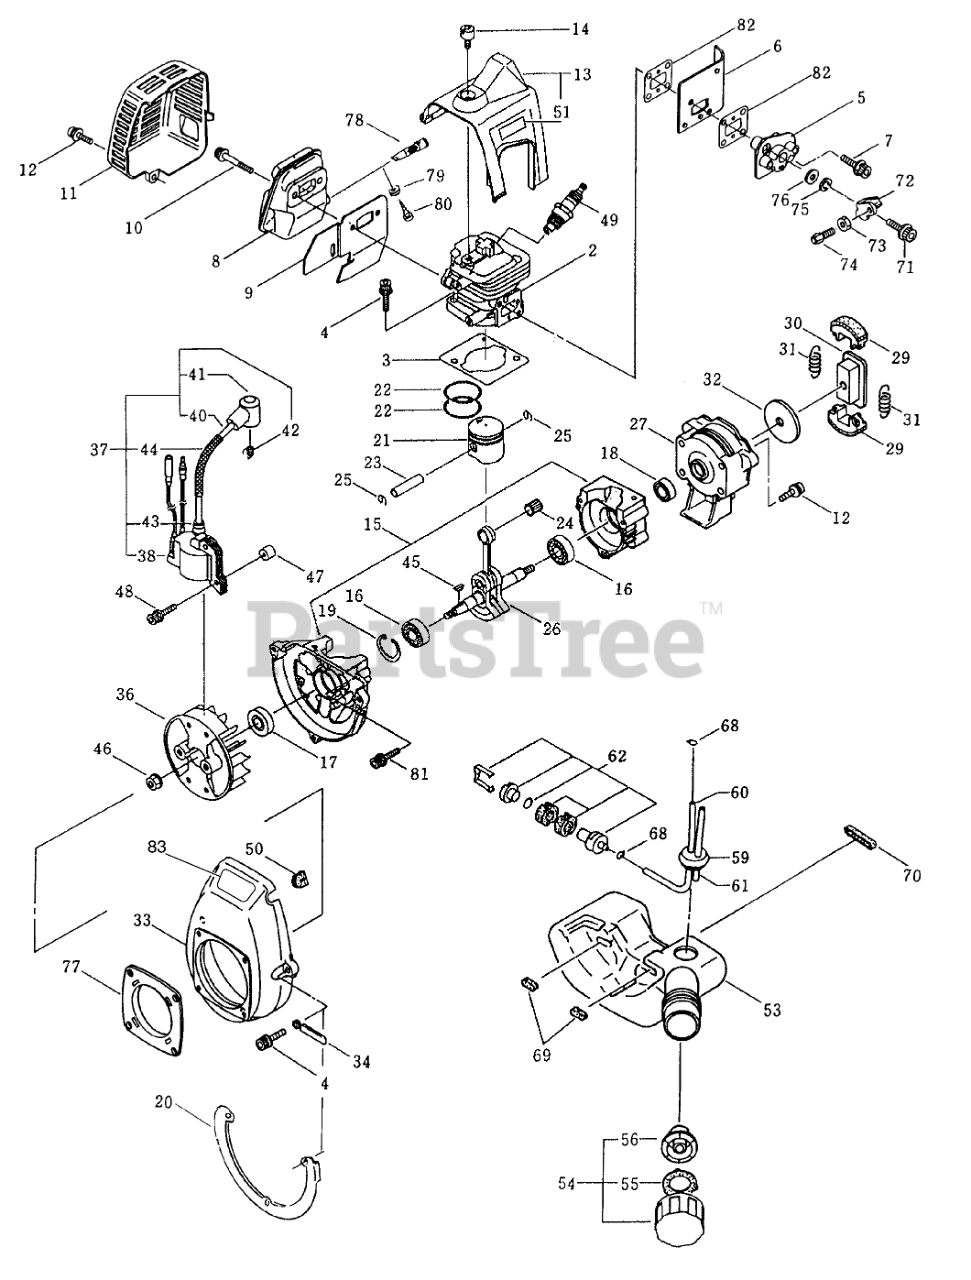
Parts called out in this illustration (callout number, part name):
2	Cylinder
3	GASKET
5	INSULATOR
6	DUCT - AIR
7	SCREW
8	MUFFLER
9	GASKET
10	CAPSCREW
11	COVER - MUFFLER
13	COVER - CYLINDER
14	COVER - KNOB,TOP
15	CRANKCASE
16	BEARING
17	SEAL - OIL
18	SEAL - OIL
19	RING - SNAP
20	PLATE
21	PISTON
22	RING - PISTON
23	PIN - PISTON
24	BEARING - NEEDLE
25	CIRCLIP
26	CRANKSHAFT
27	CASE - CLUTCH
29	SHOE - CLUTCH
30	BOSS - CLUTCH
31	SPRING
32	WASHER
33	COVER - FAN
34	CLAMP
36	FAN - ROTOR
37	Ignition Coil Assembly (Incl. Ref. #38-44)
40	CABLE - IGNITION
41	CAP - PLUG
42	CONNECTOR
45	KEY - WOODRUFF
47	SPACER
49	SPARK PLUG
50	GROMMET
51	DECAL - WARNING
53	TANK - FUEL
54	Tank Cap Assembly (Incl. Ref. #56-56)
55	GASKET
56	ASM - BREATHER
59	GROMMET
60	PIPE - FUEL
61	PIPE - RETURN
62	ASM - FUEL FILTER
71	CAPSCREW
74	ADAPTER
75	WASHER
76	WASHER
77	PLATE
78	ARRESTER - SPARK
79	WASHER
80	SCREW
81	CAPSCREW
82	GASKET
83	Decal-Toro
